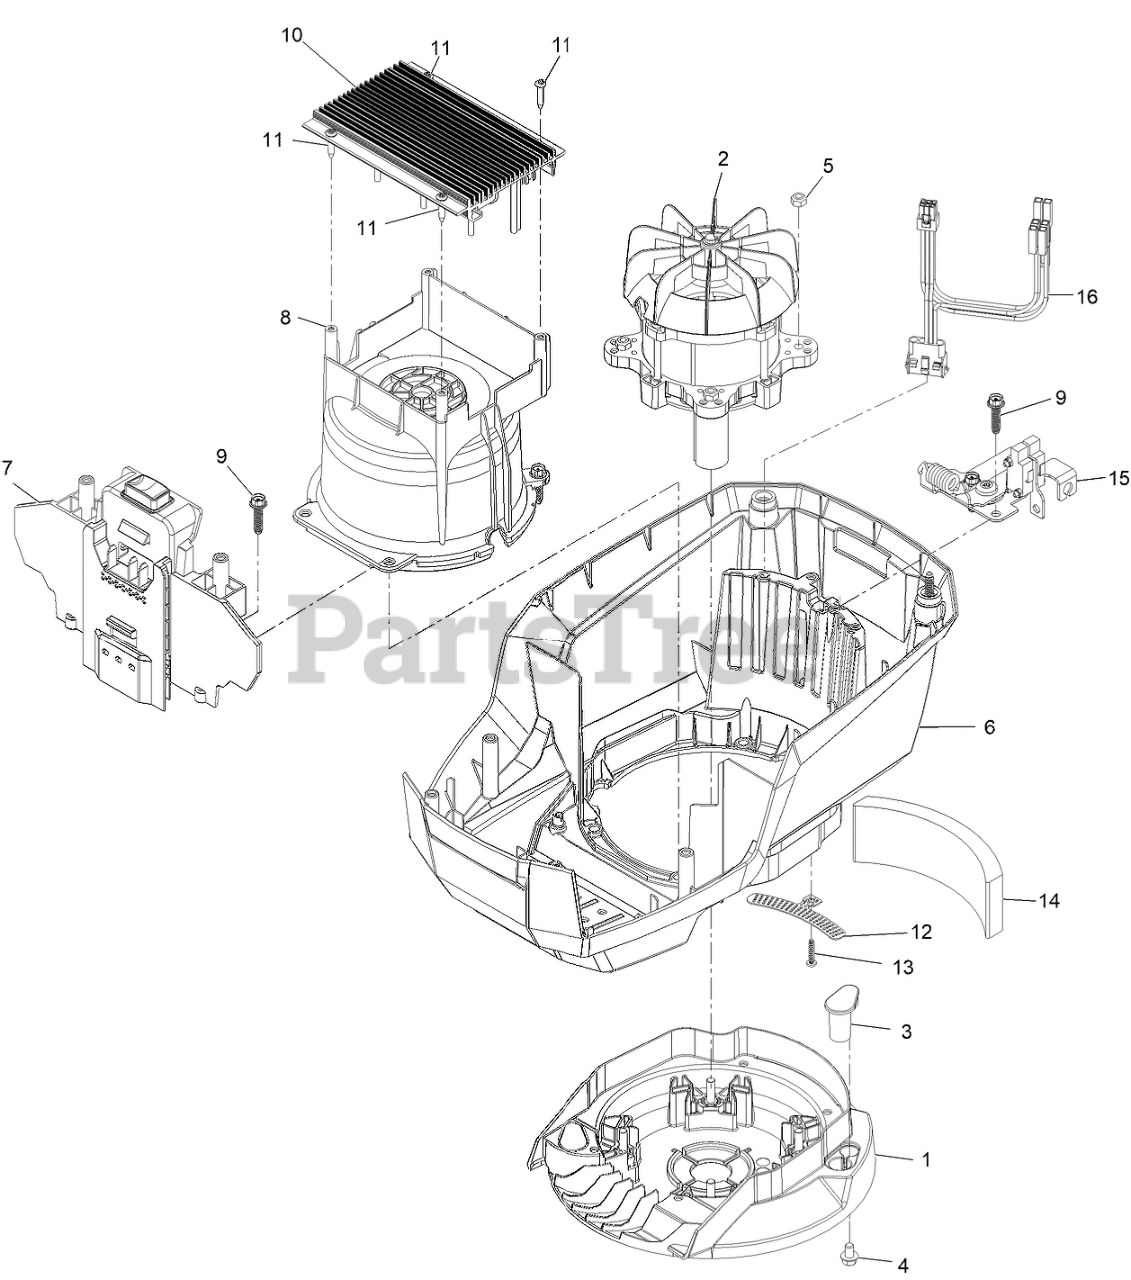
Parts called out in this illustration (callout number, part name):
1	BASE-MOUNT, MOTOR
2	Motor-2Kw
3	INSERT-MOUNT, MOTOR
5	NUT-LOCK
6	Shroud-Lower
7	BATTERY RECIEVER ASM
8	SHROUD-MOTOR
9	SCREW-FLANGE, PLASTIC
10	Controller-Motor [2 Spd]
12	BRACKET-FOAM
13	SCREW-PLASTIC, PPH
15	BAIL SWITCH ASM
16	Harness-Wire
